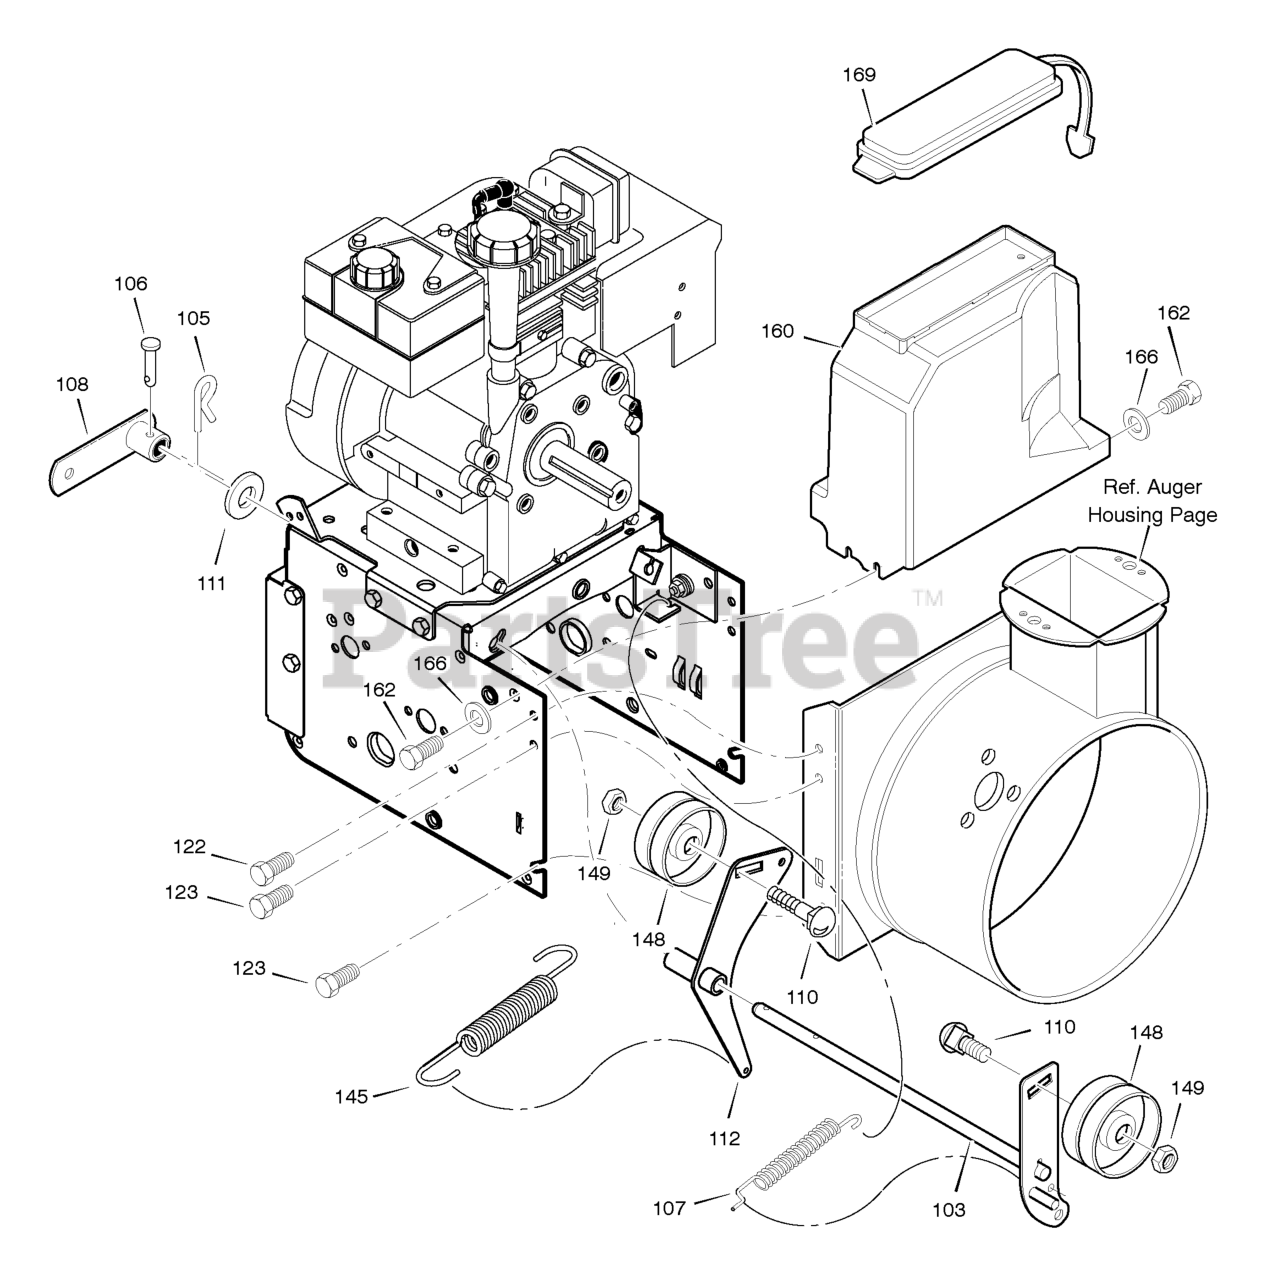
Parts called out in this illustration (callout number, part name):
103	IDLER ASSEMBLY, AUGER
105	PIN, HAIR .38DIAX1.64LG
106	PIN, CLEVIS 3/16" DIA
107	SPRING, TENSION
108	ASSY., SPRING ATTACH
110	BOLT, 3/8-16X1.25 CARR.
111	WASHER, FLAT
112	BRACKET, IDLER
122	SCREW, TAP 5/16-18 X .75
123	SCREW, TAP 5/16-18 X .50
145	SPRING, CLUTCH
148	PULLEY, IDLER
149	NUT, JAM 3/8-16
160	COVER, BELT
162	SCREW, TAP
167	WASHER, FLAT
169	LID, TOOL BOX
